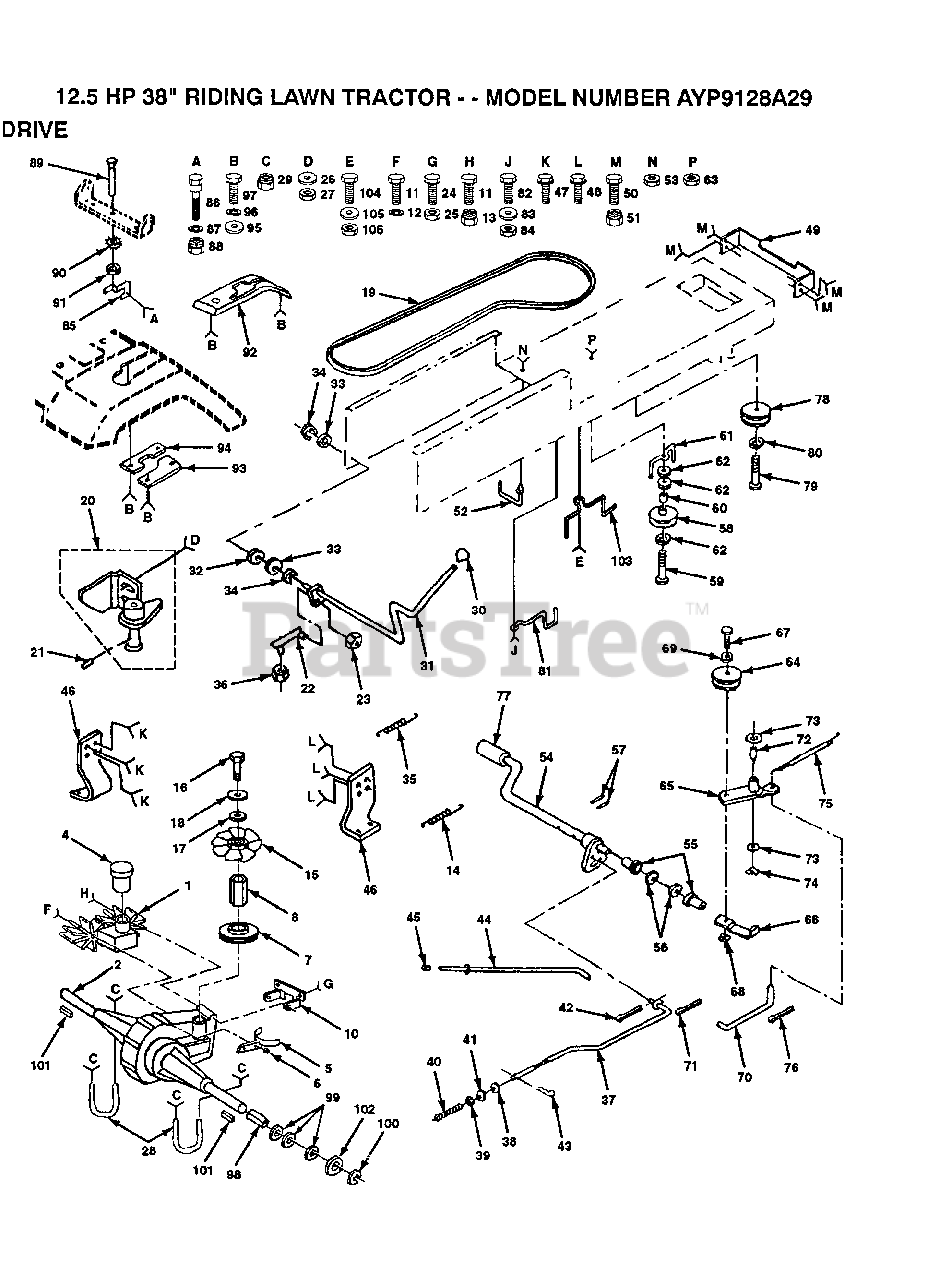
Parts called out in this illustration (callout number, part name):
1	PUMP.BDU-10S-114
2	TRANSAXLE.AGRIFAB
4	PUMP.2003081.
5	"GRD ASS'Y,BELT"
7	"PULLEY,TRANSAXLE"
8	STANDOFF
10	BRACKET
11	BOLT
12	LOCKWASHER
17	WASHER
18	LOCKWASHER
20	"FRICTION,PACK ASS"
21	"PIN,ROLL METRIC"
22	"LINK,PUMP CONTROL"
23	NUT WIZLOC T
26	WASHER
28	U BOLT
30	KNOB T (1/2-HOLE)
31	"LEVER,CONTROL"
32	"BUSHING,PIVOT"
33	"WSHER,SHIM"
34	RING T
35	"SPRING,EXTENTION"
36	NUT WIZLOC T
38	NUT
39	NUT
40	SPRING ROD LT
41	WASHER
42	SPRING.RETAINER
43	RETAINER M
44	BRAKE PARK ROD
45	PLUNGER CAP T
46	BRKT TRANSAXLE
47	SCREW GTV
48	SCREW
49	PLATE TRANS SUPT
52	"KEEPER,CENTERSPAN"
55	NYLON BEARING
56	WASHER LT
58	PULLEY.IDLER.FLAT
59	BOLT
60	SPACER T
61	BELT KEEPER LT
62	WASHER
65	ARM IDLER
66	RETAIN BELT
69	WASHER
70	"LINK, CLUTCH T"
71	COTTER PIN
72	"LY, BEARING"
73	WASHER LT
74	KLIP RING
75	"SPRING, RETURN LT"
76	COTTER PIN
77	PEDAL COVER T
79	BOLT
80	LOCKWASHER
81	KEEPER.BELT.ENG.L
82	BOLT
83	WASHER
85	"ARM,BYPASS CONTRO"
86	BOLT T
87	WASHER T
89	CONTROL BYPASS
90	LOCKWASHER
92	"CONSOLE,SHIFT FEN"
93	"PLATE,NEUTRAL RH"
94	"PLATE,NEUTRAL LH"
95	WASHER PM
96	LOCKWASHER
98	SPACER SPLIT
99	WASHER
100	E-RING LT
101	SQUARE KEY
102	WASHER
103	GUIDE BLT DR MWR
104	BOLT
105	WASHER
